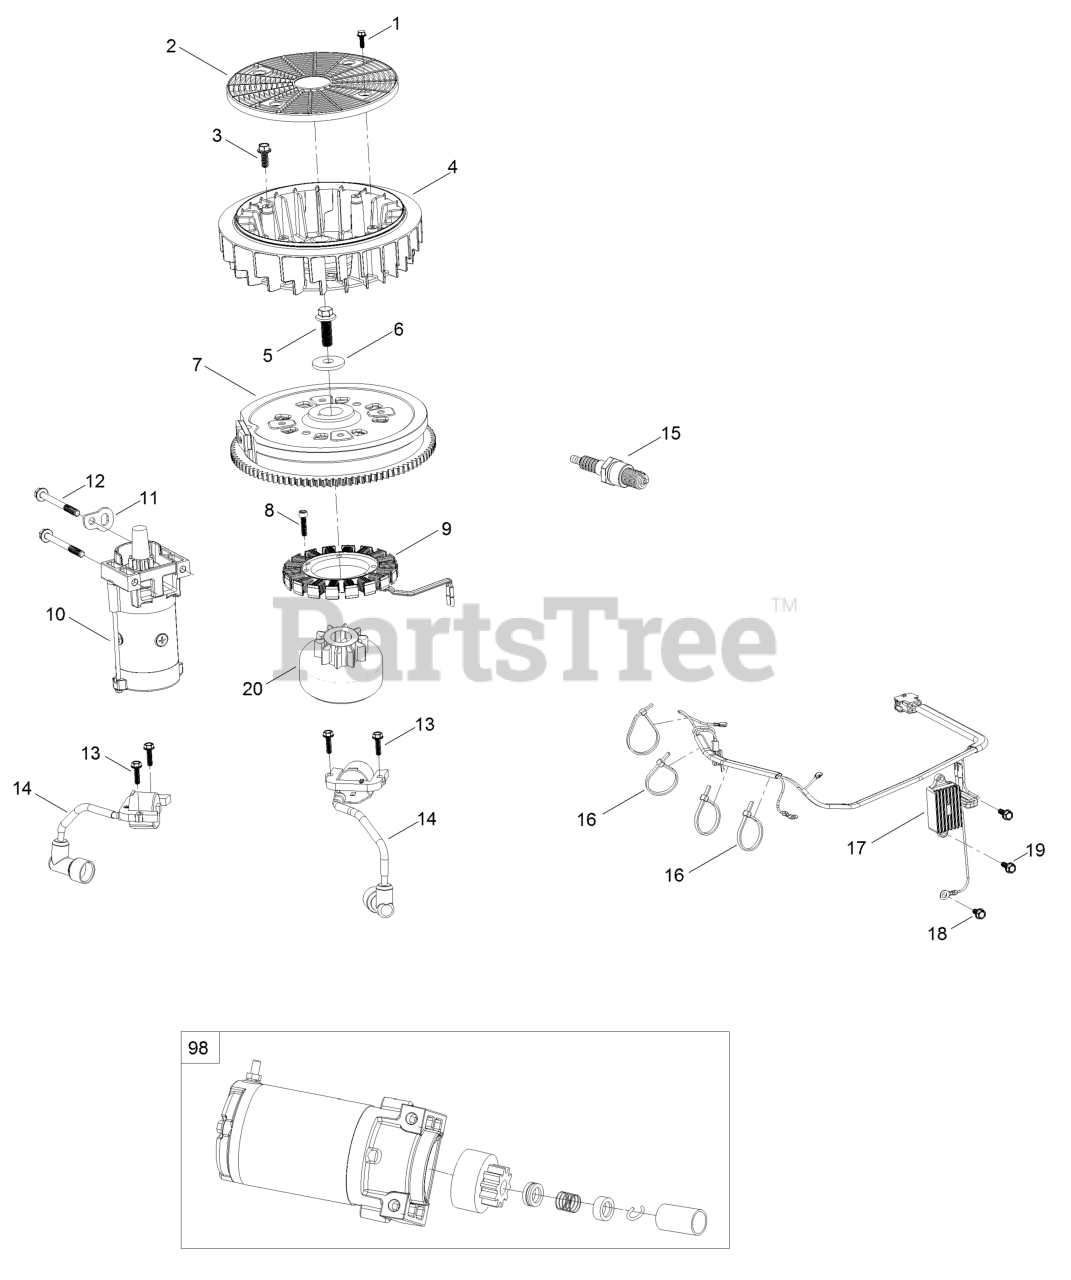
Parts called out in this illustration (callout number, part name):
1	Screw-HWH
2	Screen-Rotating
3	Screw-HWH
4	Fan-Cooling
5	Screw-HWH
6	Washer-Flat
7	Flywheel
8	Screw-HSH
9	Alternator
10	Motor-Starter
11	Bracket-Lift
12	Screw-HHF
13	Bolt-Flange
14	Ignition Coil ASM
15	Spark Plug
16	Tie-Zip
17	Regulator-Voltage W/Harness
18	Screw-HHF
19	Screw-HHF
20	Pinion-Starter
98	Starter Repair Kit
